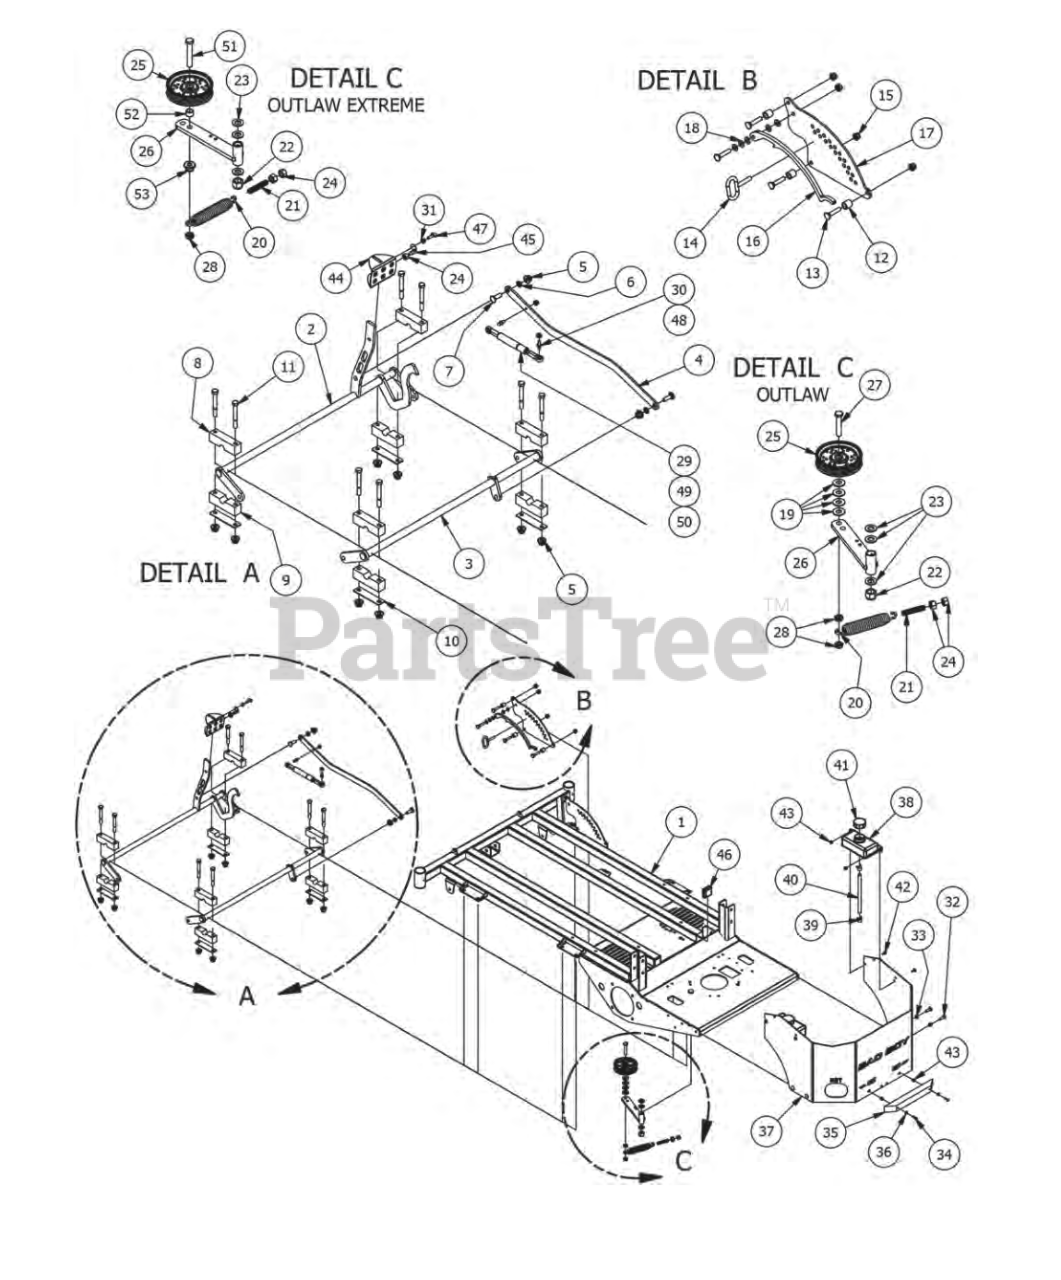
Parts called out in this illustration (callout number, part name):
1	2015 Standard/Extreme Outlaw Frame
2	2015 Outlaw Act Bar Assembly (Front)
3	2015 Outlaw Act Bar Assembly (Rear)
4	Outlaw Deck Linkage Rod
5	1/2-13 Nylon Flange Nut-Orange
6	Bushing-SF-1620-4
7	1/2 x 1-1/2 Carriage Bolt
8	Two Piece Pillow Block (Male)
9	Two Piece Pillow Block (Female)
10	Two Piece Pillow Block Strap
11	1/2" x 4" Bolt (Grade 8)
12	3/4 OD x 1/2 ID x 3/4 Length
13	3/8 x 1 3/4 Carriage Bolt
14	Deck height lever pin
15	3/8" Nylock Flange Nut
16	Outlaw Deck Lever Lock
17	Outlaw Height Indicator Plate (Outer)
18	.390 x .750 x .062 Nylon Washer
19	1/2" Brass Washer (Base Only)
20	2009 Deck/Pump Idler Spring
21	All Thread-pump Idler Tensioner
22	5/8 Std NC Nylock Nut
23	.635 ID Plastic Washer
24	1/2" Hex Nut
25	43/4 Idler Pulley - ABFI-76
26	Deck Idler
27	1/2" x 3" Hex Bolt (Base Only)
28	1/2" Nylcock Nut (1/2 Jam)
29	200 lb Gas Spring-54" Deck outlaw
30	10mm Damper Ball Stud-Steering
31	5/16" Flange Nut
32	3/8" x 1 1/4" Carriage Bolt
33	3/8 Nylock Nut
34	1/4-20 x 1-1/4 GR 5 Hex Bolt
35	14" Rubber Bumper
36	1/4" Flat Washer
37	2015 Outlaw Rear Plate
38	Expansion Tank Outlaw
39	5/8 Wire Clamp-Outlaw Only
40	5/8 Braided Hose
41	Hydraulic Tank Cap
42	1/4" x 3/4" Carriage Bolt
43	1/4-20 Nylon Insert flange Nut
44	Outlaw Deck Lift Pedal
46	2X2 Frame Plug
47	5/16-18 x1 Thumb Screw Zinc
48	13mm Damper Ball Stud for 72" Deck only
49	250 lb Gas Spring -61" Deck Outlaw
50	300 lb Gas Spring - 72" Deck Outlaw
51	1/2" x 3" Hex Bolt (Extreme Only)
52	1/2" x 1/2 Spacer (Extreme Only)
53	1/2"-13 Nylon Flange Nut (Extreme Only)
